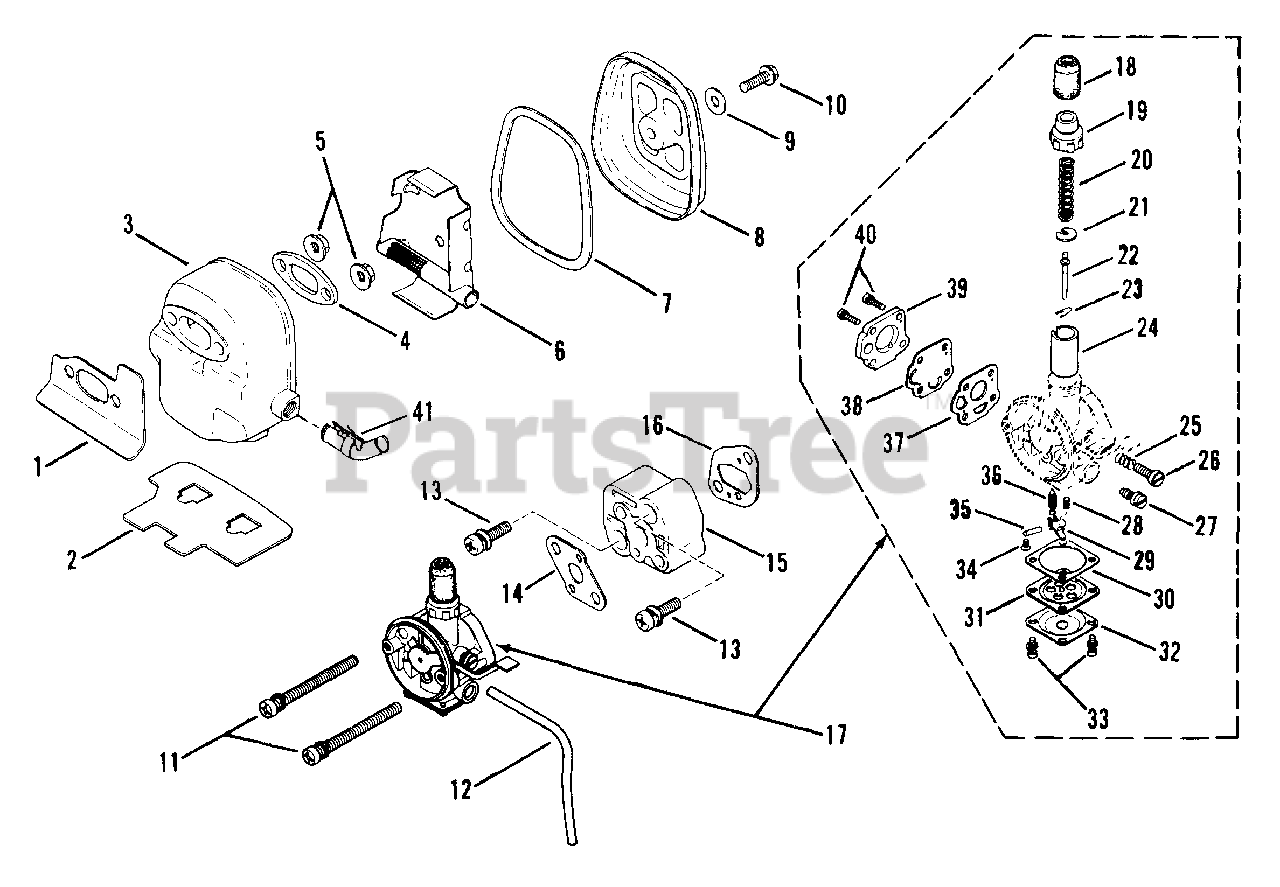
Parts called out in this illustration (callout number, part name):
1	GASKET, Muffler
3	BODY, Muffler
4	PLATE, Muffler
5	LOCKNUT, Sems
6	PLATE, Spark Arrestor
8	COVER, Muffler
10	BOLT, Flange
11	SCREW/WASHER, Carb.
12	TUBE, Overflow
13	SCREW/WASHER
14	GASKET, Carburetor
15	INSULATOR, Carburetor
16	GASKET, Insulator
17	CARBURETOR ASSEMBLY
18	CAP, Rubber
19	CAP, Mixing Chamber
20	SPRING, Throttle
21	RETAINER, Spring
22	NEEDLE, Jet Assembly
23	CLIP, Needle
24	VALVE, Throttle
25	SPRING, Throttle Adj. Screw
26	SCREW, Throttle Adj.
27	NEEDLE, Main Jet Assm'y.
28	SPRING, Inlet Valve
29	ARM, Float
30	GASKET, Main Diaphragm
31	DIAPHRAGM, Main Assm'y
32	COVER, Main Diaphragm
34	SCREW, Float Pin Set
35	PIN, Float
36	VALVE, Float
37	GASKET, Pump Cover
38	DIAPHRAGM, Pump
39	COVER, Pump
41	NOZZLE, Exhaust
